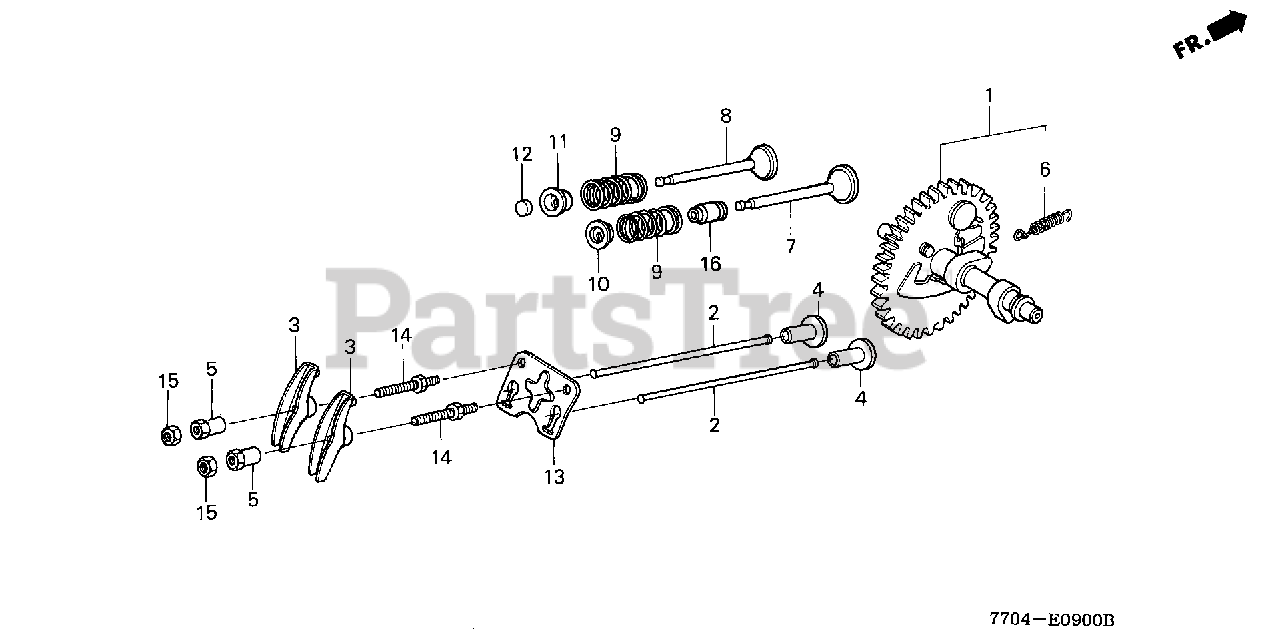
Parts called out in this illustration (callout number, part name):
1	CAMSHAFT ASSY.
2	ROD, PUSH
3	ARM, VALVE ROCKER
4	LIFTER, VALVE
5	PIVOT, ROCKER ARM
6	SPRING, WEIGHT RETURN
7	VALVE, IN.
8	VALVE, EX.
9	SPRING, VALVE
10	RETAINER, IN. VALVE SPRING
11	RETAINER, EX. VALVE SPRING
12	ROTATOR, VALVE
13	PLATE, PUSH ROD GUIDE
14	BOLT, PIVOT (8MM)
15	NUT, PIVOT ADJUSTING
